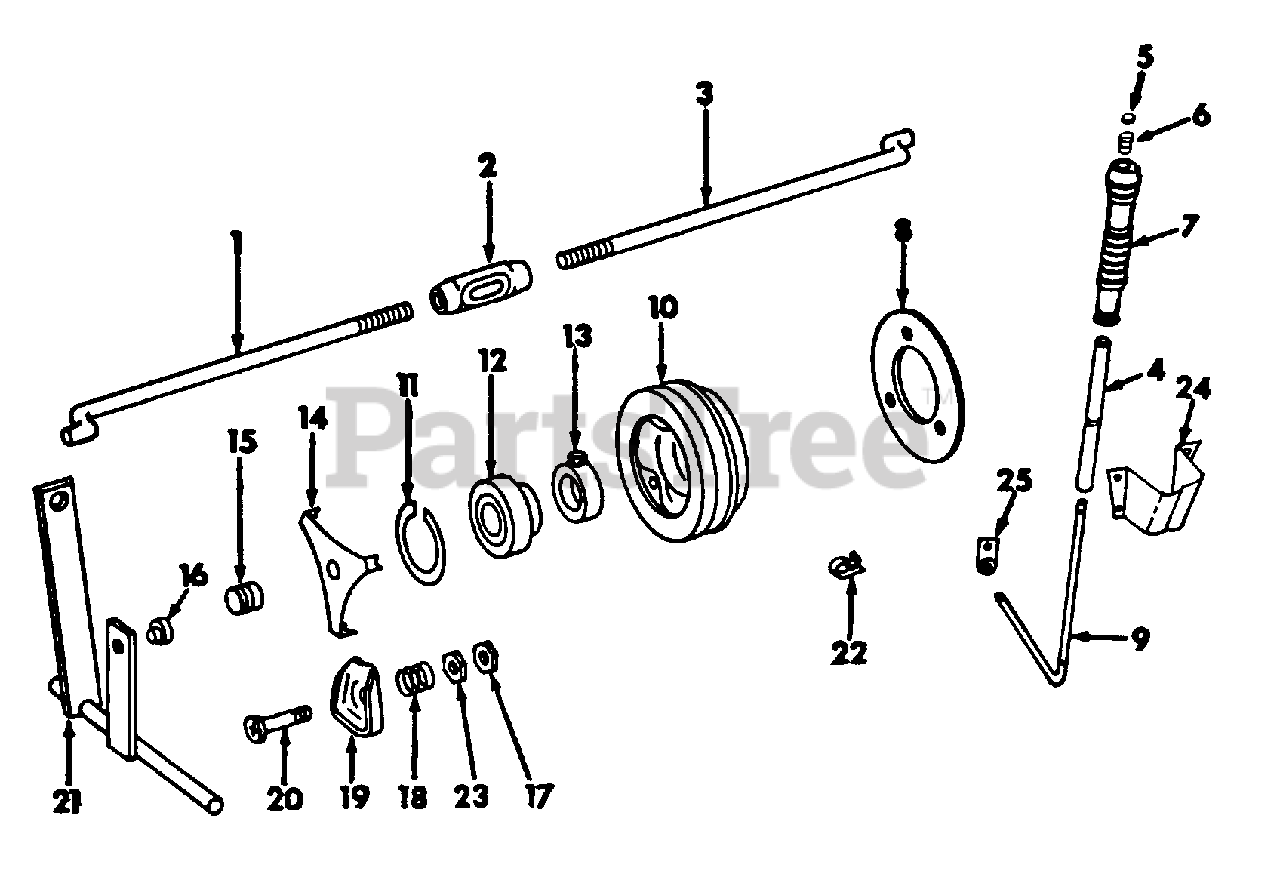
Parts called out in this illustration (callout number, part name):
2	Turnbuckle, Rod
3	Rod, Rear Clutch
5	Spacer, Handle
6	Spring, Handle Return
7	Grip, Handle
8	Plate, Pressure
9	Rod, PTO Control
10	Pulley, Mower Actuating
11	Ring, Snap 2.197 O.D., For Pulley
12	Bearing, Ball
13	Collar w/Set Screw & Lock Nut, Brg
14	Spring, Pressure
15	Button, Thrust
16	Button, Wear
17	Nut, 1/4-28 Hex Jam
18	Spring, Compression
19	Lever, Throw-Out
20	Screw, Special Machine
21	Shaft, Clutch
22	Spring, Friction Disc
23	Nut, 1/4-28 Hex
24	Bracket Assy, PTO Handle
25	Lever Assy, PTO
